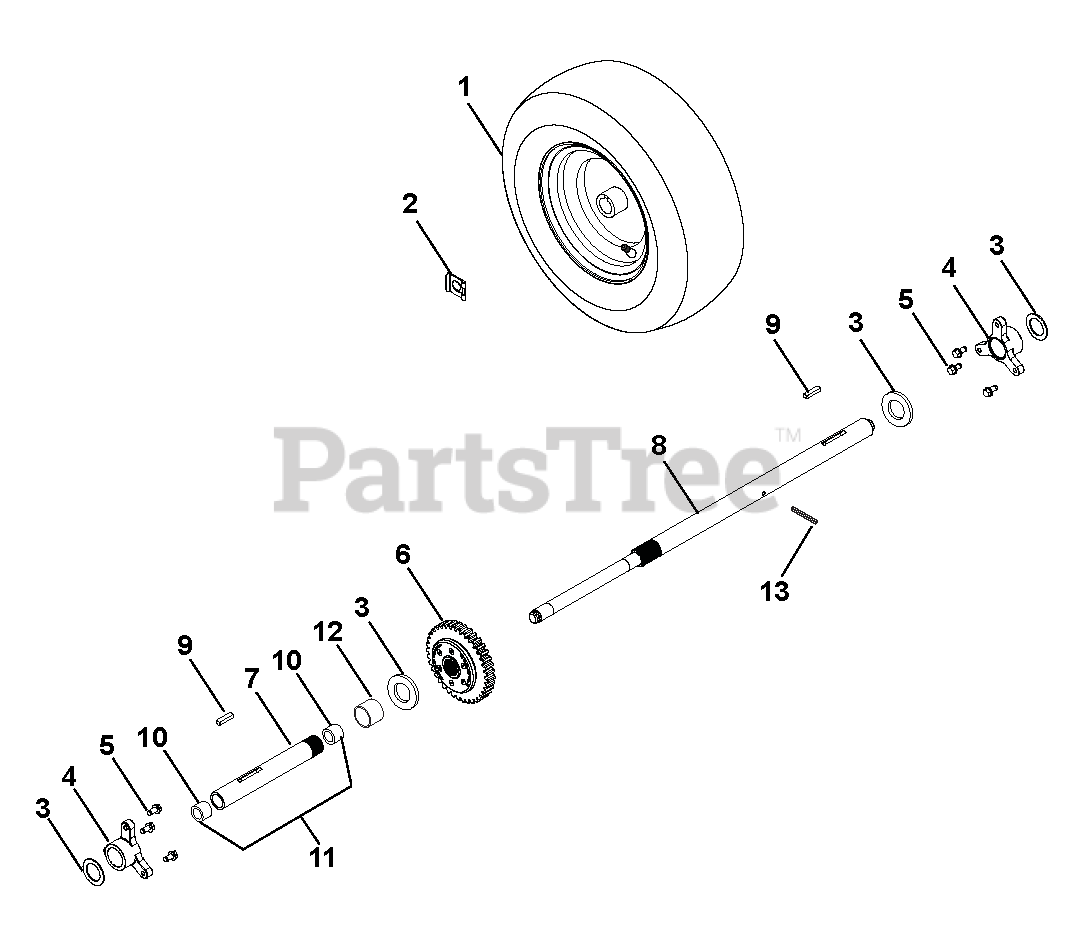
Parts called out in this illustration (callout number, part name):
1	TIRE/WHEEL,RH 15X5.00-6 REMOTE
2	CLIP, SNAP .625 DIA
3	WSHR-FL-STL 1.010X1.505X.062YZ
4	BUSHING, AXLE
5	SCR-TAP .25-20X.50 HWH TR YWZ
6	DIFFERENTIAL, AUTOMATIC
7	AXLE, SHORT - DIFFERENTIAL
8	AXLE, LONG - DIFFERENTIAL
9	KEY-RECT .25X.188X1.00
10	BSHG-SLV .706X.764X.75 BRZ
11	AXLE, DIFFERENTIAL W/BUSHINGS
12	BSHG-SLV, 1.012X1.125X1.00
13	PIN-ROLL .188X1.25
